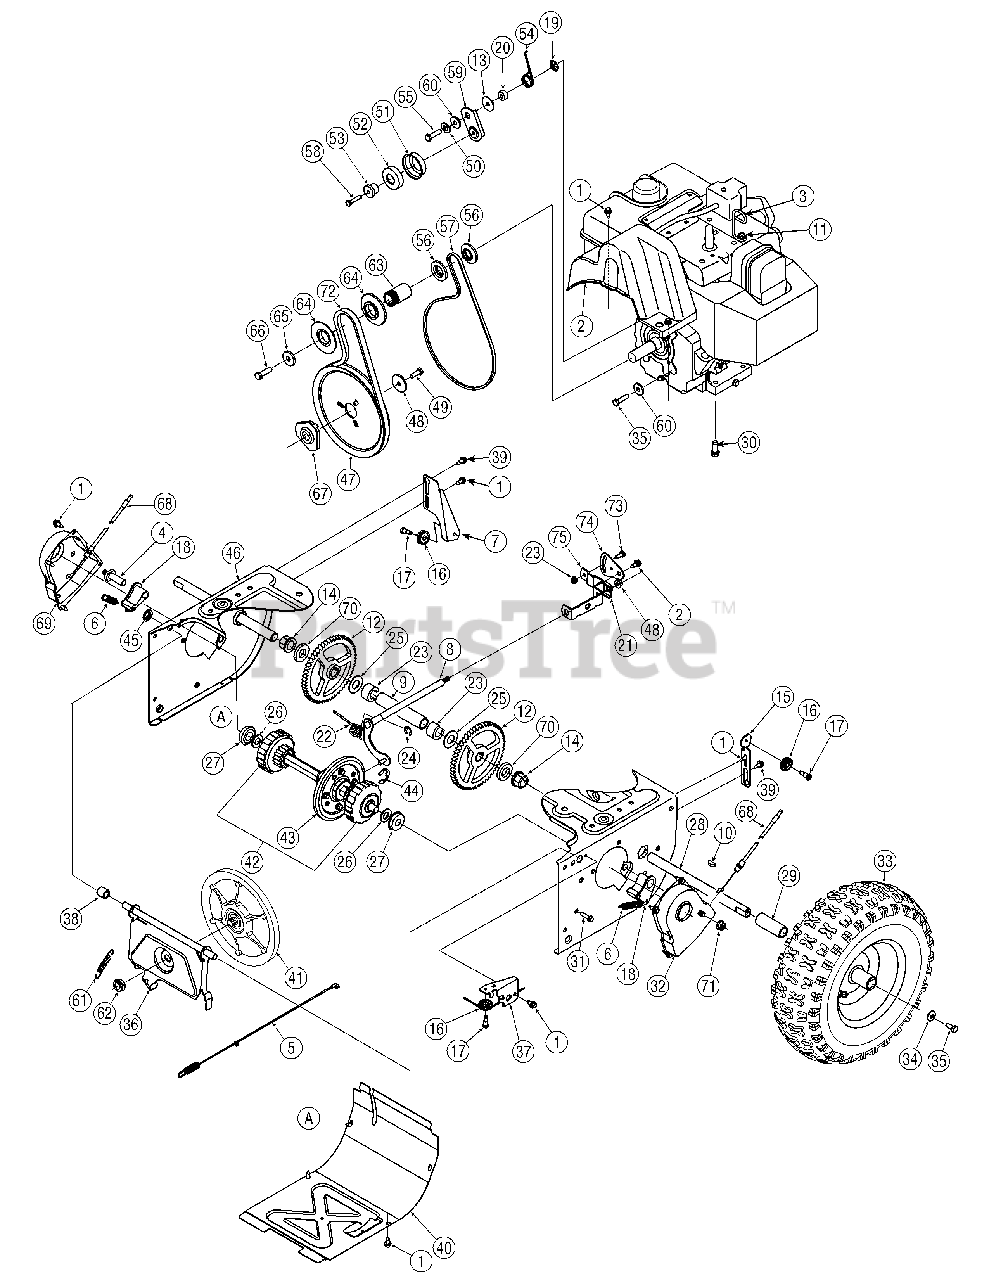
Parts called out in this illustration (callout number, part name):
1	AB Screw, 1/4-20 x 0.625
2	Belt Cover
3	Cable Guide
4	Actuator Shaft
5	Drive Clutch Cable
6	Extension Spring
8	Shift Rod Assembly
9	Axle Support Tube
10	Hi Pro Key
11	TT Screw, 5/16-18 x 1.00
12	Gear, 56T
13	Flat Washer
14	Hex Flange Bearing
16	Cable Roller
17	C Screw, 1/4-28 x 0.375
18	Dogg Assembly - LH
18	Dogg Assembly - RH
19	Push-on Nut
20	Spacer
21	Shift Bracket Spacer
22	Torsion Spring, .750ID x .968 LG
23	Spacer
24	E Ring
25	Flat Washer, .76 x 1.49 x .06
26	Flat Washer
27	Ball Bearing
28	Axle
29	Spacer
30	TT Sems Screw, 3/8-16 x 1.0
31	TT Screw, 1/4-20 x 1.0
34	Bell Washer
35	Hex Bolt, 5/16-24 x 0.75
38	Spacer
39	Shoulder Screw
42	Drive Shaft Assembly
43	Friction Wheel Assembly
43	Friction Wheel Rubber Only
44	Retainer Ring
45	Speed Nut
47	Auger Pulley
48	Flat Washer
49	Hex Bolt, 5/16-24 x 0.875
50	Lock Washer
51	Bearing Sleeve
52	Ball Bearing
53	Spacer
54	Torsion Spring
55	Hex Screw, 5/16-24 x 1.25
56	Pulley Half
57	V-Belt, 2L x 33
58	TT Screw, 1/4-20 x 1.25
59	Drive Clutch Idler Bracket
60	Shoulder Spacer
61	Extension Spring
62	Jam Lock Nut, 5/8-18
63	Spacer
64	Pulley Half
65	Flat Washer
66	Hex Bolt, 3/8-24 x 1.25
67	Pulley Adapter
68	Steering Cable
70	Axle Spacer
71	Flange Lock Nut, 3/8-16
72	V-Belt,.500 x 35.00 Lg
73	Hex Screw, 1/4-20 x .620
